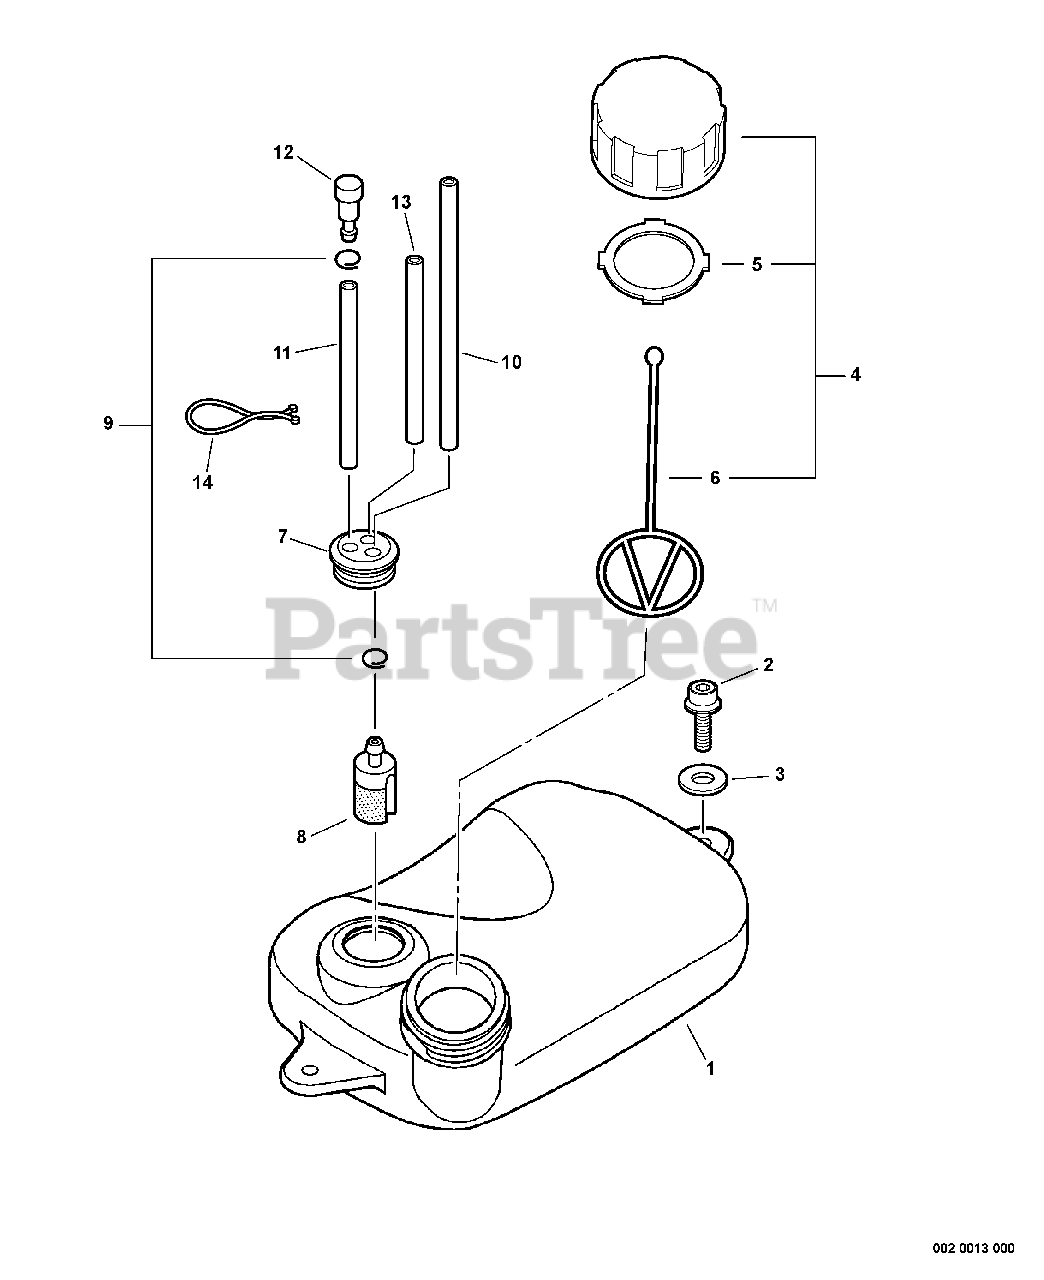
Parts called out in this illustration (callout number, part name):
1	TANK, FUEL
2	BOLT 5×20
3	WASHER 5.5×16×2T
4	CAP ASSY, FUEL
5	GASKET, FUEL CAP
6	CONNECTOR, CAP L= 100 MM
7	GROMMET, FUEL
8	FILTER, FUEL
9	CLIP 6 MM
10	PIPE, FUEL 3×5×210 BLACK
11	PIPE, FUEL 3x-5x-70 BLACK
12	VENT ASSY
13	PIPE, FUEL 3×6×125
14	CLIP, TUBE
